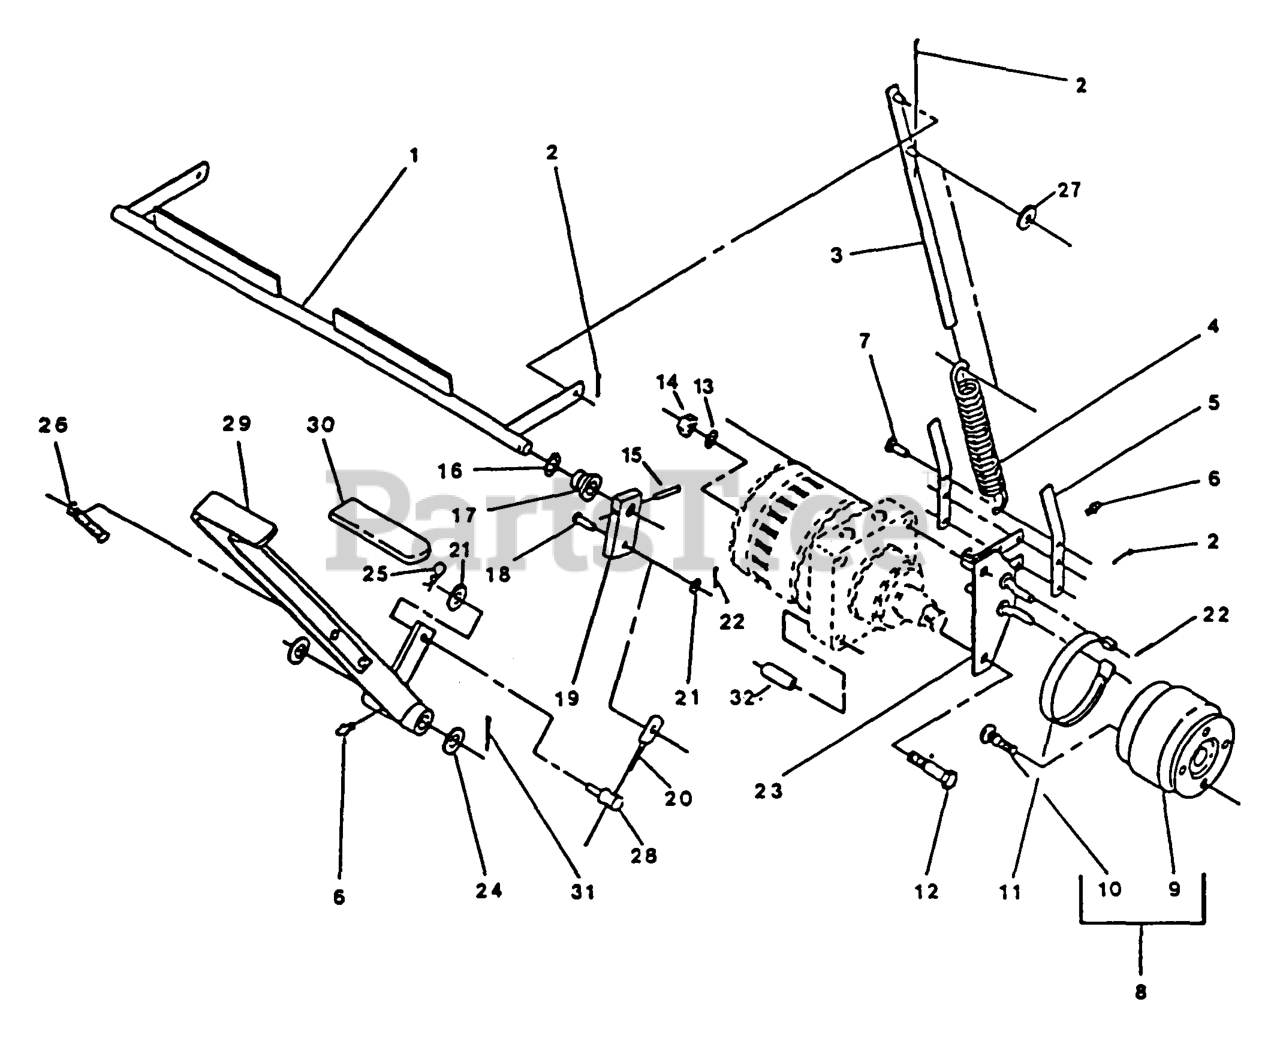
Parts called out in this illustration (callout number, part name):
1	WLD,ROD LOCKOUT
4	SPRING,EXTENSION
5	LINK,BRAKE CONNECTING
8	HUB/BRAKE DRUM ASSY
10	BOLT,HUB
11	BAND,BRAKE
18	PIN-CLEVIS
23	BRAKE BRKTW/ZERK LH
25	PIN-COTTER
26	SPRING,BRAKE HANDLE
29	HANDLE & TRIGGER, BRAKE
30	GRIP-LEVER
32	SPACER,MOTOR MOUNTING
